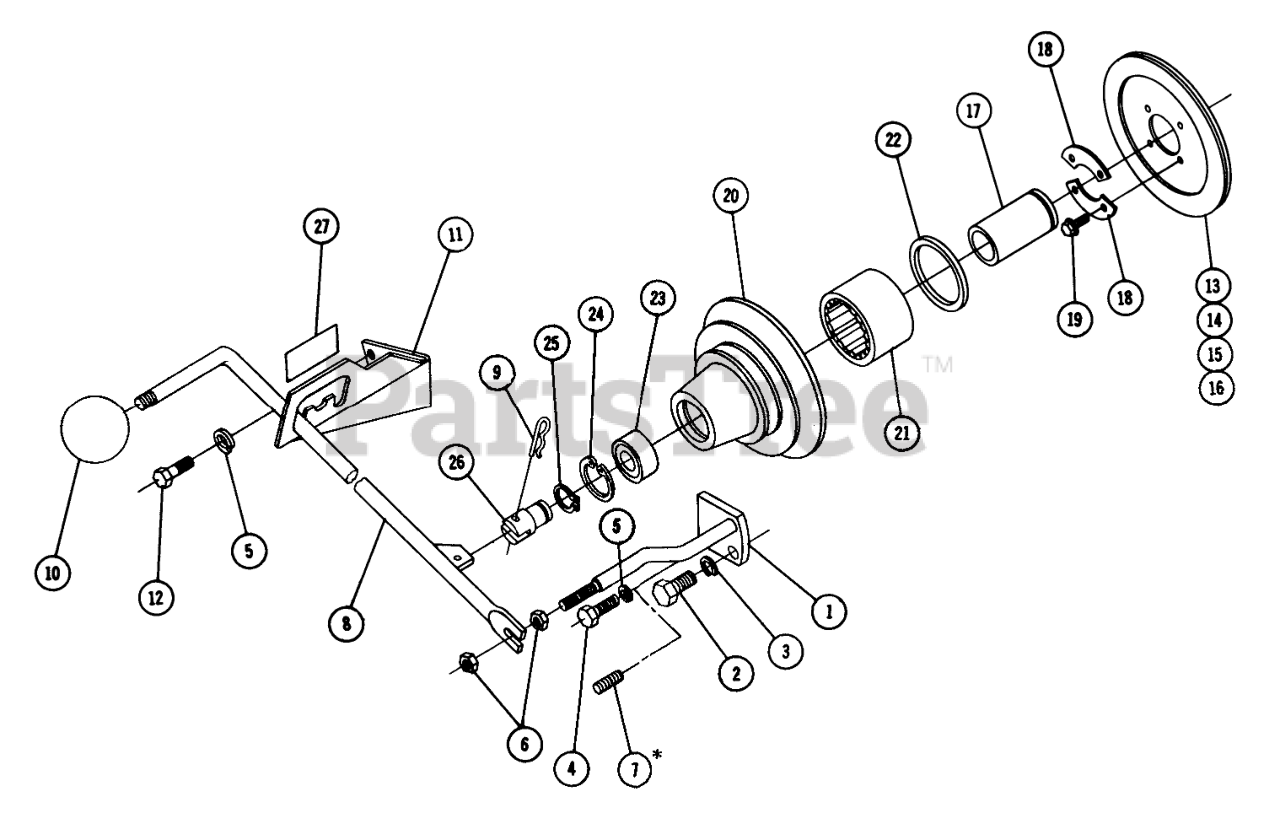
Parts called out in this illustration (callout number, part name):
1	PLATE & ROD ASSEM R
2	Bolt, 7/16 14 x 1
3	Lockwasher 3/8
4	Bolt 5/16-18 x
5	Lockwasher
7	Set Screw-5/16-18 x1/2
7	Set Screw 3/8-16 x 3/4
8	ROD ASSY
9	Hairpen
10	Knob
11	Bracket
12	Bolt Hex 5/16-18
13	L/A CLUTCHPLATE&FACI
14	Clutch Plate
15	CLUTCH FACING
16	RIVET-BRASS
17	RACE-BEARING
18	RETAINER
19	Bolt, 1/4-20 Whizlock
20	Clutch Housing
21	Seal
22	SEAL-OIL
23	Bearing
24	Ring-Snap
25	RING-SNAP, EXTERNAL
26	SHAFT
27	DECAL
